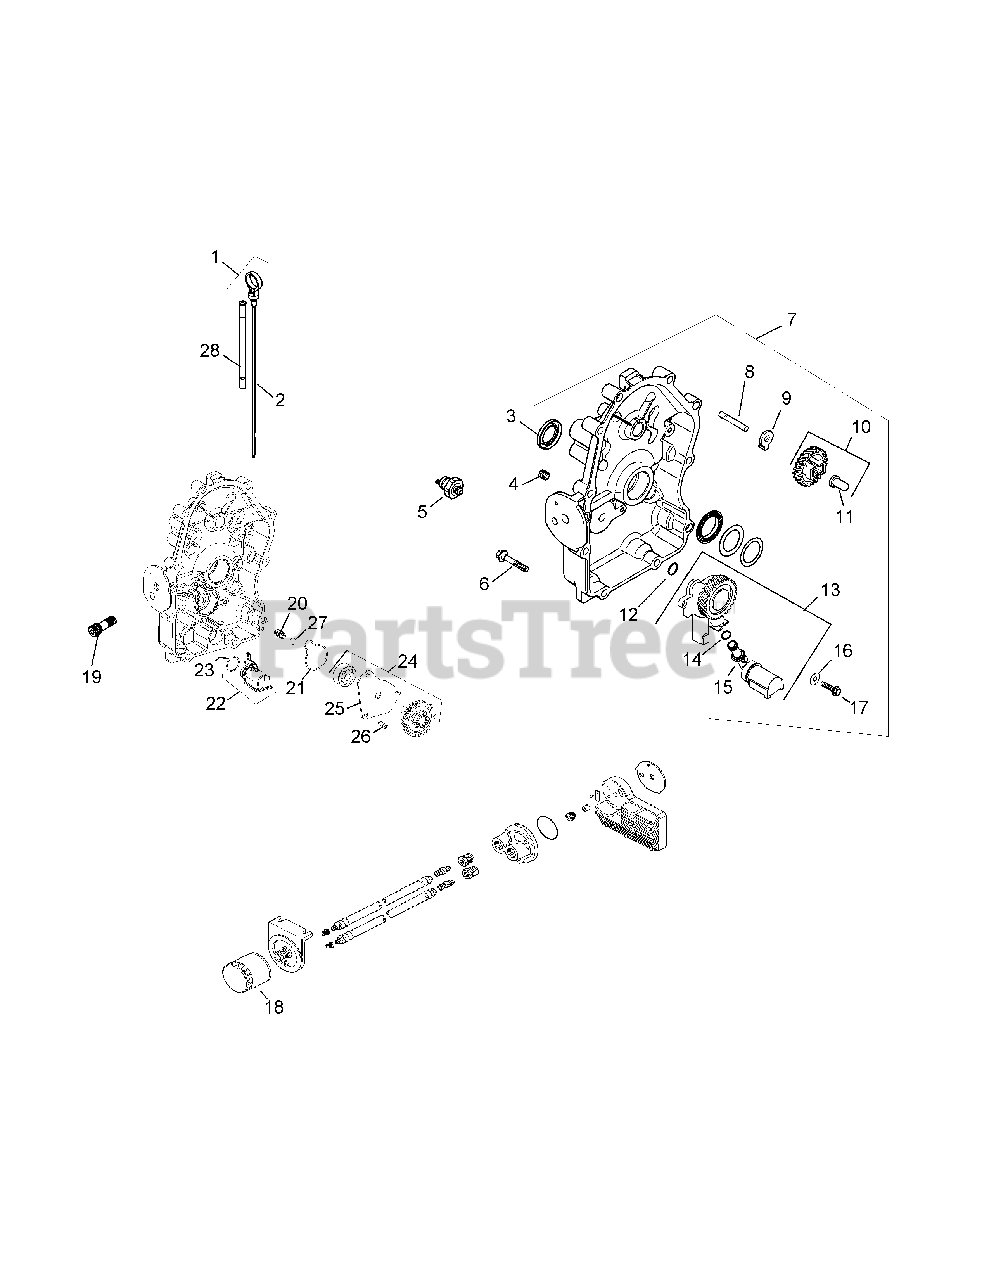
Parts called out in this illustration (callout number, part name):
1	Dipstick/Dipstick Tubes Kit
4	Countersink Pipe Plug, 1/8
5	Oil Pressure Switch
6	Flange Screw, M8 x 1.25 x 45
7	Closure Plate Assembly
8	Governor Gear Shaft
10	Governor Gear Kit w/ Pin
11	Governor Regulating Pin
13	Oil Pump Assembly Kit
14	Oil Pick-Up O-Ring
16	Flat Washer, 1/4 x 5/8
17	Thread Forming Screw
19	Oil Filter Nipple
20	Compression Spring
21	Oil Pump Cover Seal
22	Oil Pick-Up Assembly
23	Oil Pick-Up O-Ring
24	Oil Pump Assembly
25	Oil Pump Cover
26	Button Head Screw
27	Pressure Relief Ball
28	Dipstick Tube
